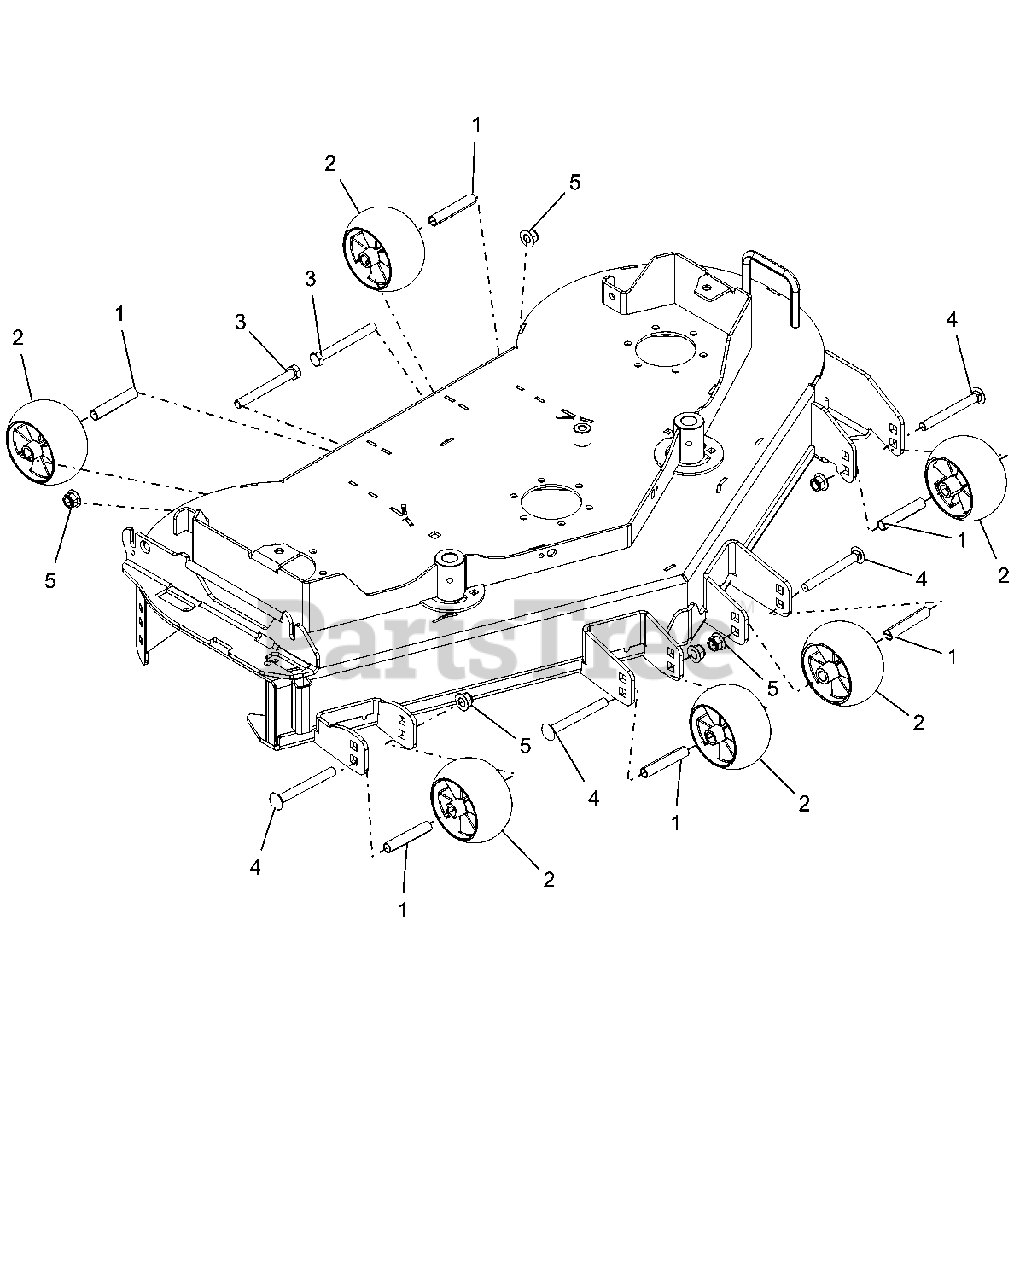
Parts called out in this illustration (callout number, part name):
1	SPACER, .510X.625X3.35
2	ANTI-SCALP WHEEL - 5X3 CTR
3	BLT-HEX .50-13X4.50 GR5 YWZC
4	BLT-RDHDSQNK .50-13X4.50 G5 YWZC
5	NUT-LK-NYL-FLG .50-13 YWZC
